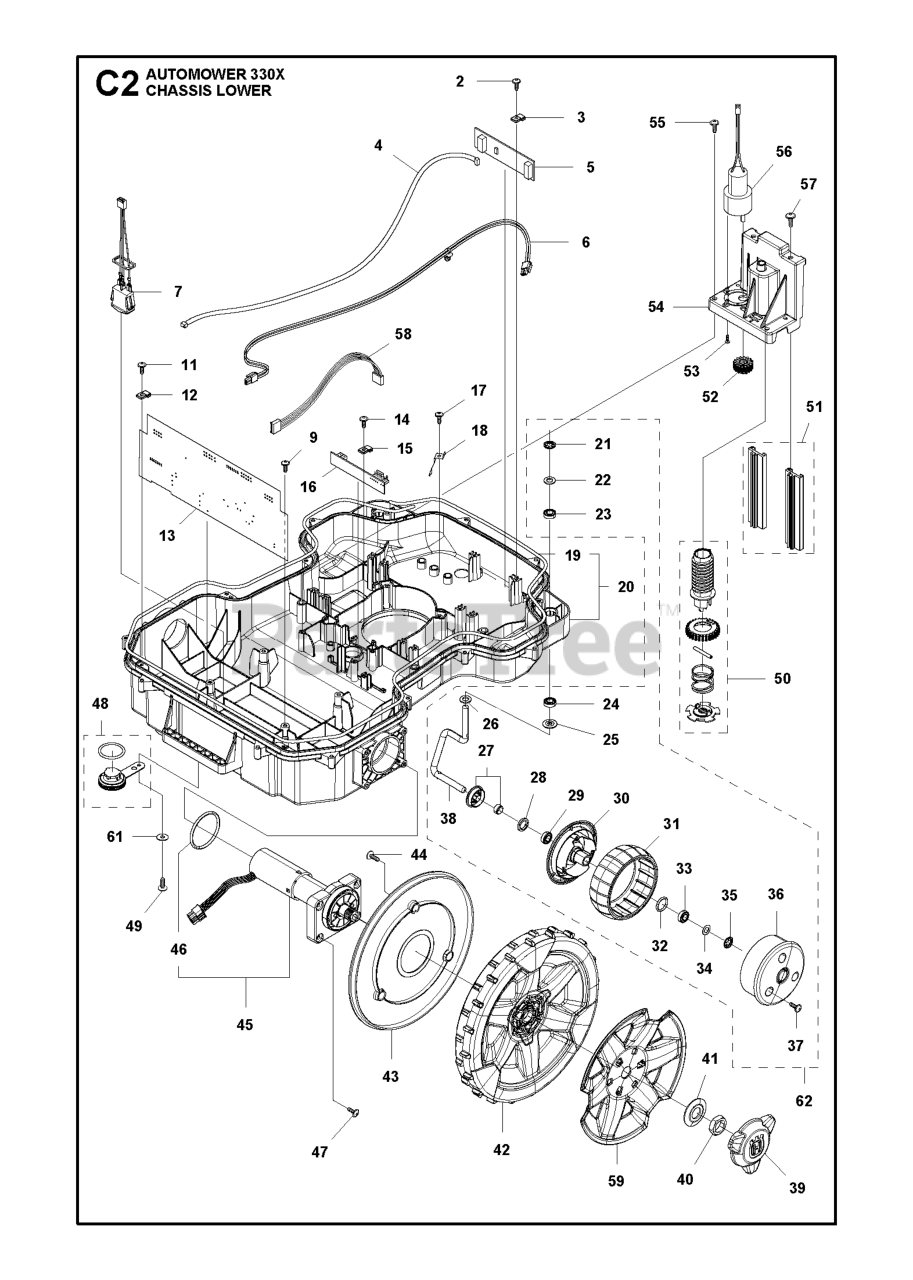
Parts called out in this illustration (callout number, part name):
1	BATTERY LI-ION
2	SCREW 14MM
4	LOOM LOOP SENSOR
5	PRINTED CIRCUIT ASSY PCBA LOOP
7	LOOM ON/ OFF
9	SCREW ITXPANT
10	HOLDER TWIST LOCK
11	SCREW 14MM
14	SCREW 14MM
17	SCREW 14MM
18	SPRING GUIDE HEIGHT ADJUSTMENT
19	SEALING STRIP
21	LOCK WASHER PUSH-ON TYPE P 8 S
22	WASHER DIN 988 13X8X0.5
23	BALL BEARING SINGLE ROW S688
24	BALL BEARING SINGLE ROW S688
25	WASHER FRONT WHEEL CENTER HOLE
26	WASHER DIN 988 13X8X0.5
27	SHIELD KIT
28	SEALING 12X18X3
29	BALL BEARING SINGLE ROW S688
30	WHEEL FRONT WHEEL INSIDE
31	WHEEL RUBBER TYRE
32	O-RING 2,62X15,54
33	BALL BEARING SINGLE ROW S688
34	WASHER DIN 988 13X8X0.5
35	LOCK WASHER PUSH-ON TYPE P 8 S
36	WHEEL FRONT WHEEL OUTSIDE
37	SCREW 14MM
38	SPINDLE SPINDLE FRONT WHEEL RI
39	HUB CAP REAR WHEEL NO CENTER P
40	HEXAGON THIN NUT
41	WASHER WASHER REAR WHEEL 16X40
42	WHEEL ASSY D249 BLACK
43	COVER REAR WHEEL
44	SCREW 14MM
47	SCREW ITXPANT
49	SCREW 14MM
51	BEARING KIT
55	SCREW 14MM
58	LOOM HEIGHT ADJUSTMENT
59	WHEEL COVER REAR WHEEL
62	WHEEL KIT FRONT
